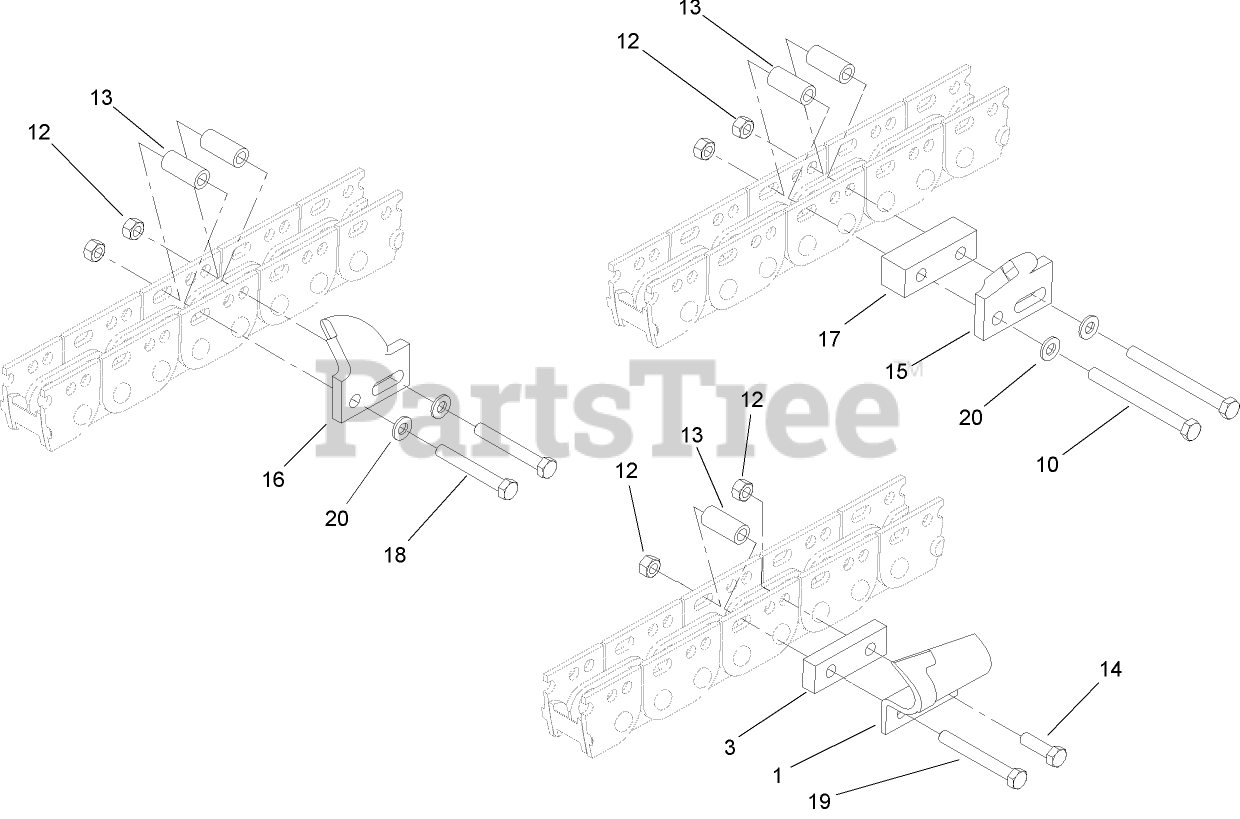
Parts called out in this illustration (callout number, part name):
1	TOOTH-SOIL, LH
3	SPACER-CUT, 5 INCH
10	SCREW-HH
12	NUT-LOCK
13	SPACER-TUBE
14	SCREW-HH
15	TOOTH- ROCK, LH
16	TOOTH-ROCK, RH
17	SPACER-CUT, 6 INCH
18	SCREW-HH
19	SCREW-HH
20	WASHER-FLAT
